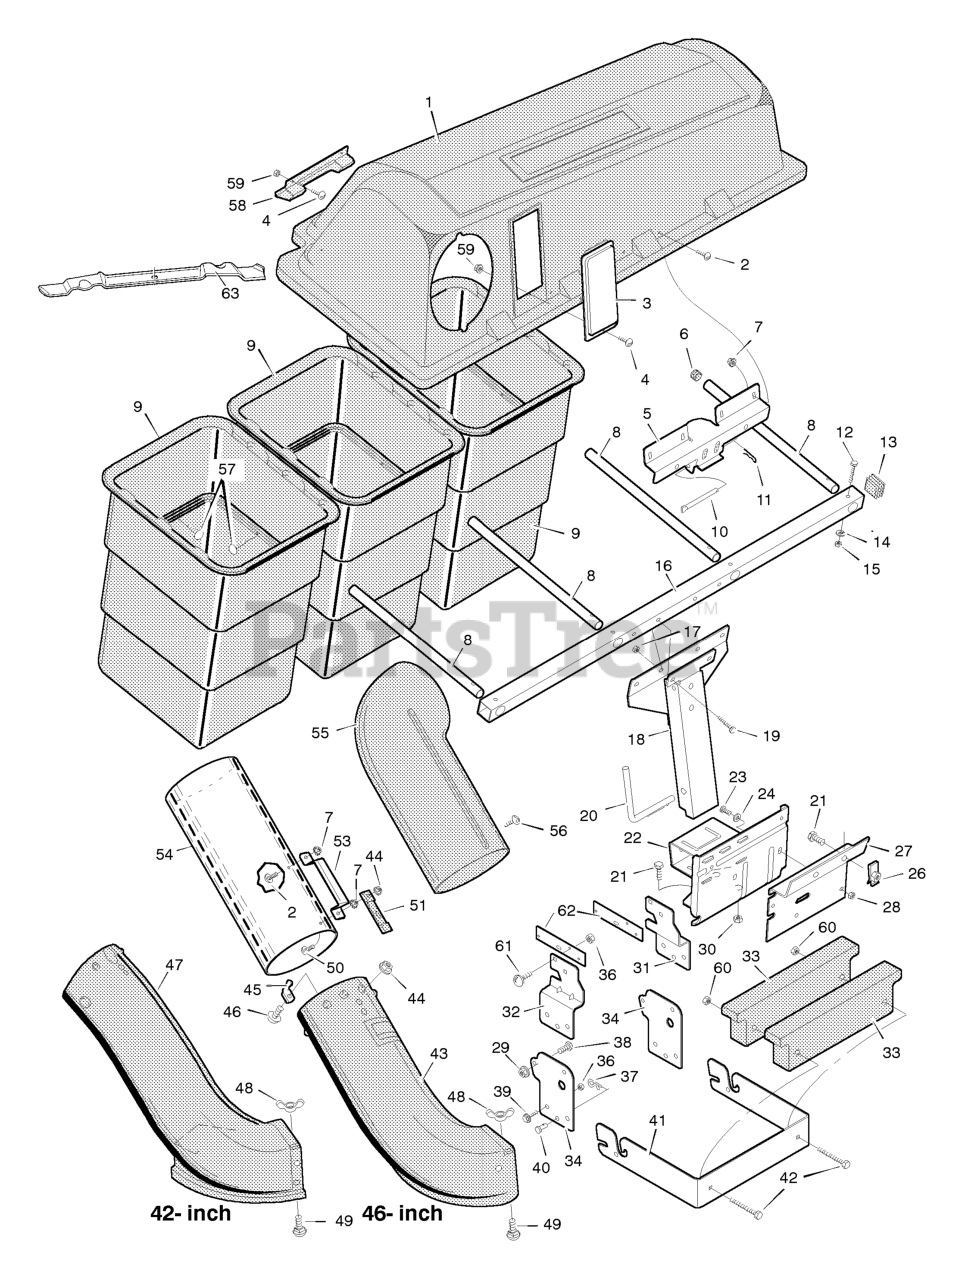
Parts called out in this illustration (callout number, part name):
1	Cover, Bagger
5	Hinge, Bracket
7	Nut, Hex
8	Tube, Container
9	Container
10	Pin, Hinge
11	Pin, Hair
13	Plug
14	Lockwasher
16	Tube, Support
17	Nut
18	Channel Assembly
20	Pin, Channel Mount
21	Bolt, Hex
22	Plate, Mounting
23	CAPSCREW, Hex Head, 5/16-18 x 1
24	Washer
27	Adapter, Mounting Plate
28	Nut, Flange
29	Nut, Flange
30	Nut, Hex
31	Bracket, Left Hanger
32	Bracket, Right Hanger
33	Weight, Front
34	Bracket, Hanger
36	Nut
37	Pin, Hair
38	Bolt
40	Pin, Clevis
41	Bracket, Front Weight
43	Extension, Chute
44	Locknut, Flange
45	Pin, Latch
46	Bolt, Carriage
47	Extension, Chute
48	Wingnut
49	Bolt, Carriage
51	Latch, Rubber
53	HANDLE, Connect Tube
54	Tube, Connecting
57	Fastener, Panel
58	Handle, Plastic
59	Nut, Hex
60	Nut
62	Plate, Support
63	Blade, 46"
